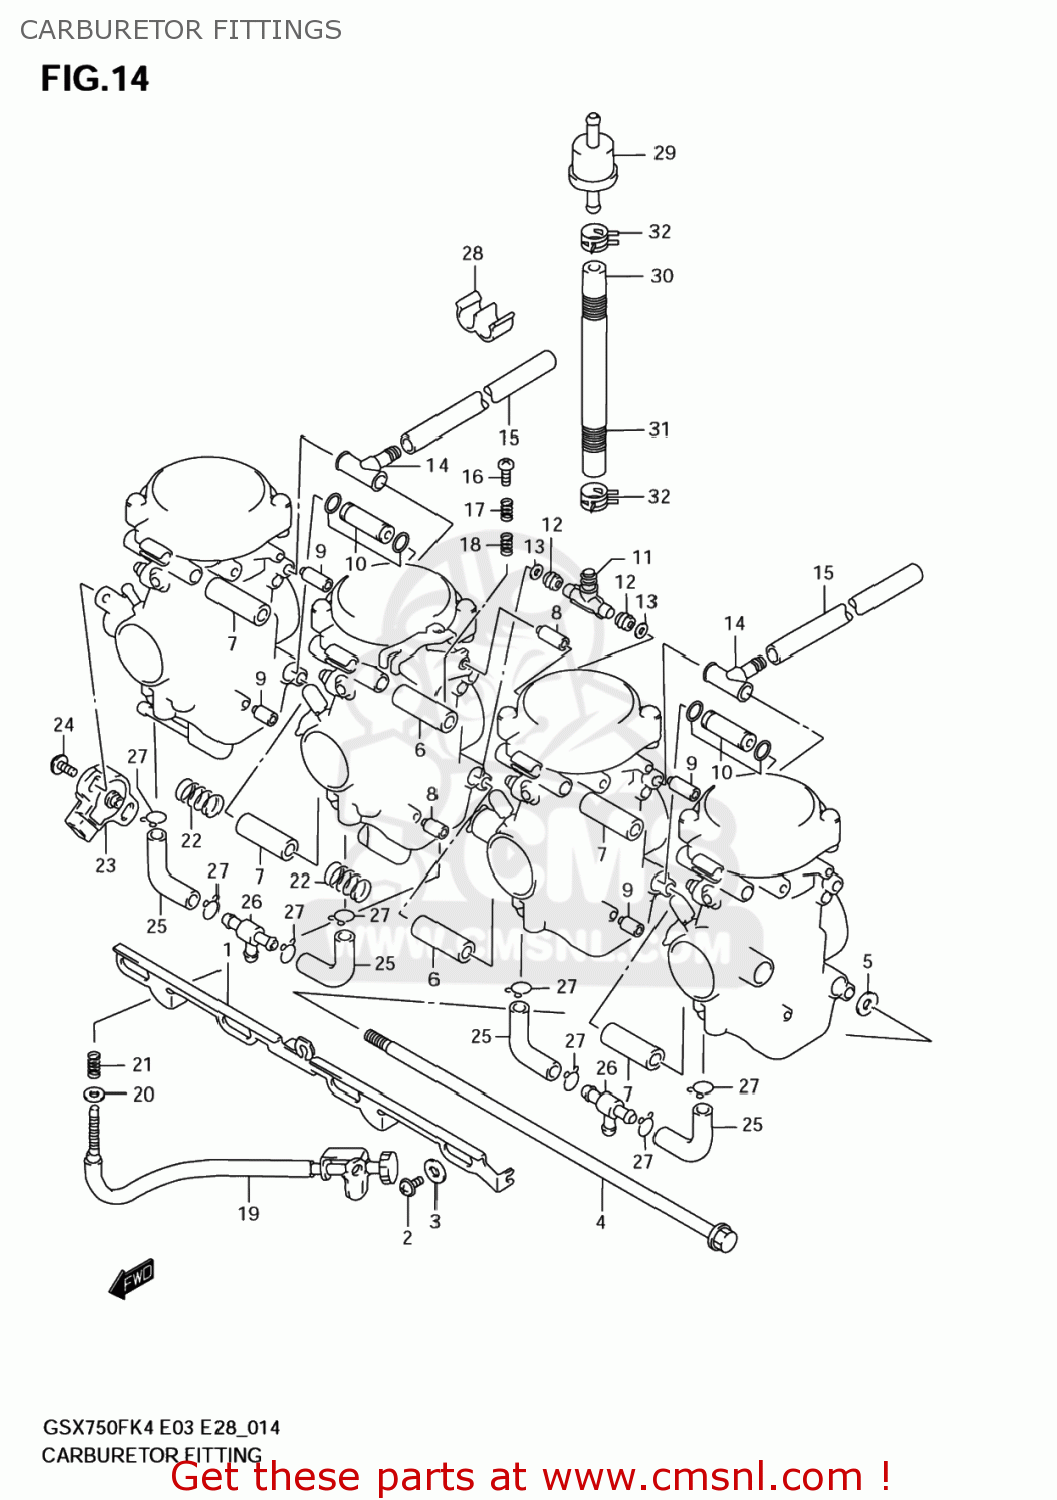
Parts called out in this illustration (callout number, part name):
1	LEVER
2	SCREW
3	PACKING
4	BOLT
5	WASHER
6	PIPE
7	PIPE
8	ROD
9	ROD
10	PIPE
11	NIPPLE
12	SEAL
13	WASHER,DRAIN PLUG
14	HOSE
15	HOSE(7X10.2X475)
16	SCREW
17	SPRING
18	SPRING,THROTTLE SCREW
19	SCREW,ADJUST
20	WASHER,STARTER SHAFT
21	SPRING
22	SPRING
23	SENSOR ASSY,THROTTLE
24	SCREW,SENSOR
25	HOSE
26	NIPPLE
27	CLIP
28	CLIP
29	STRAINER,FUEL
30	HOSE(7X12X600)
31	SPRING
32	CLIP
